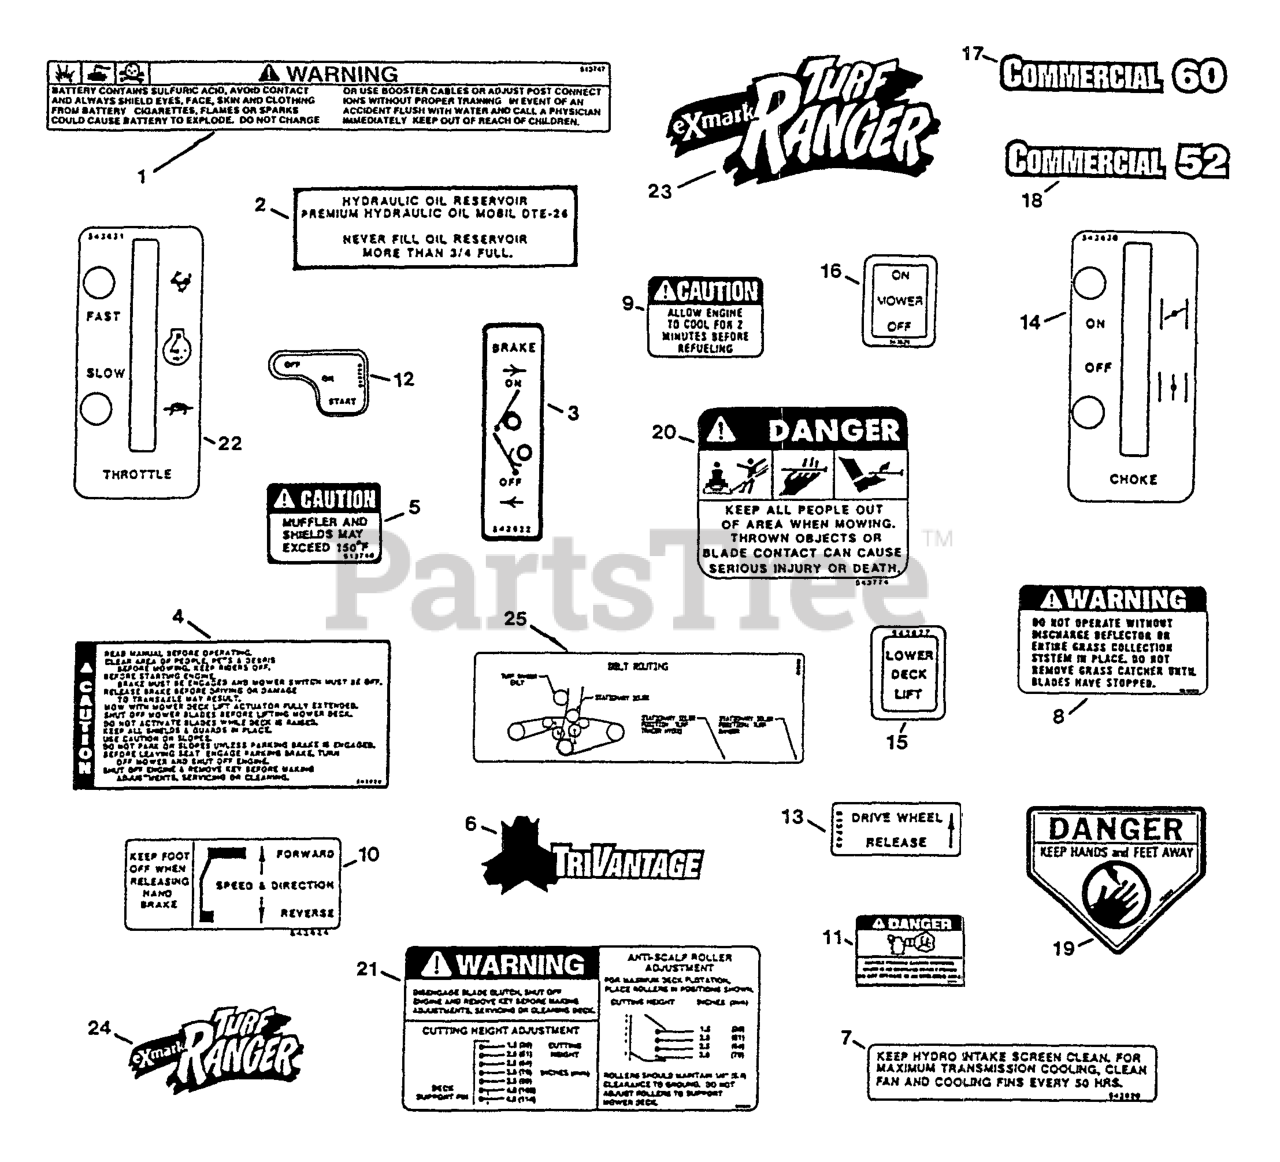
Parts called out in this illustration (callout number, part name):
1	DECAL-BATTERY
7	DECAL,INTAKE
8	DECAL-WARNING, DISCHARGE
10	DECAL,FOOT PEDAL
15	DECAL-DECK LIFT
16	DECAL-MOWER SWITCH
17	DECAL,COMMERCIAL 60
18	DECAL,COMMERCIAL 52
19	DECAL-DANGER
20	DECAL-DANGER
23	DECAL,SWASH RANGER
25	DECAL,BELT ROUTING
